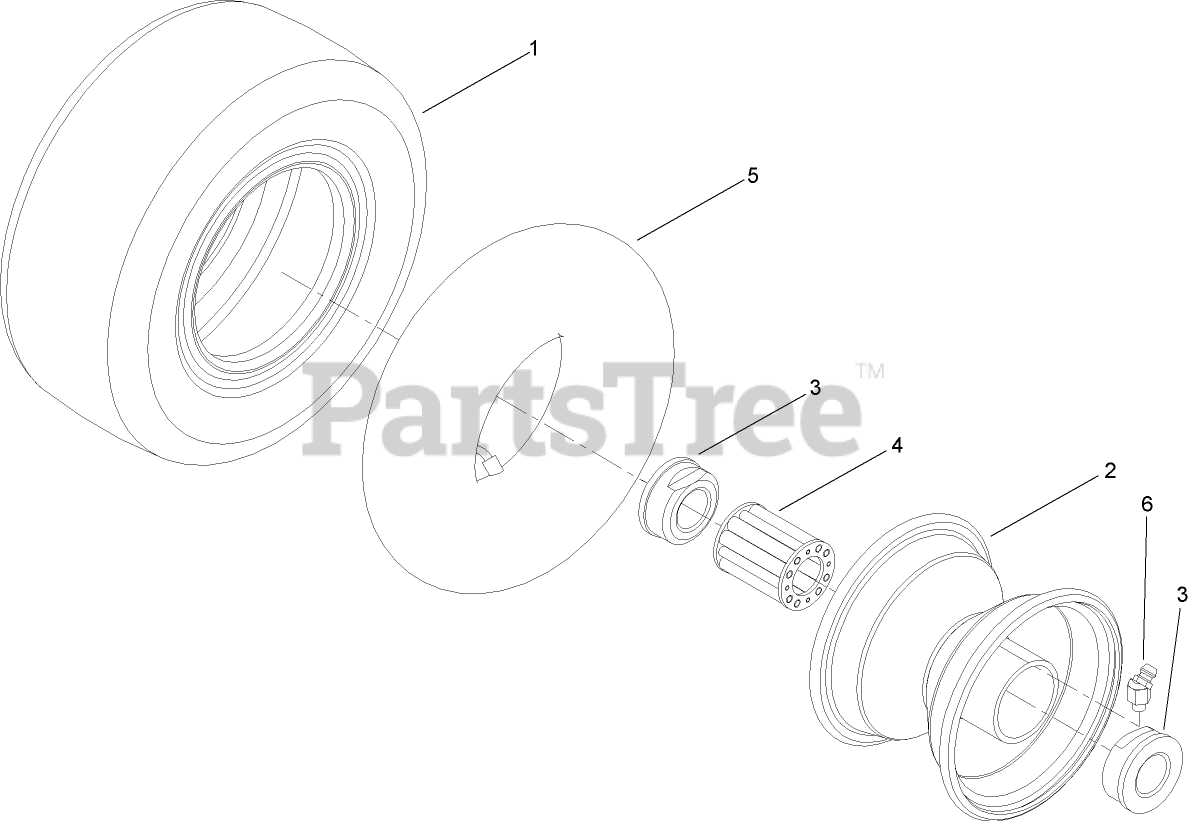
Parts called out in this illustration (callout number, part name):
2	RIM ASM
3	BEARING-OUTSIDE
4	BEARING-ROLLER
6	FITTING-LUBE, 45 DEG
